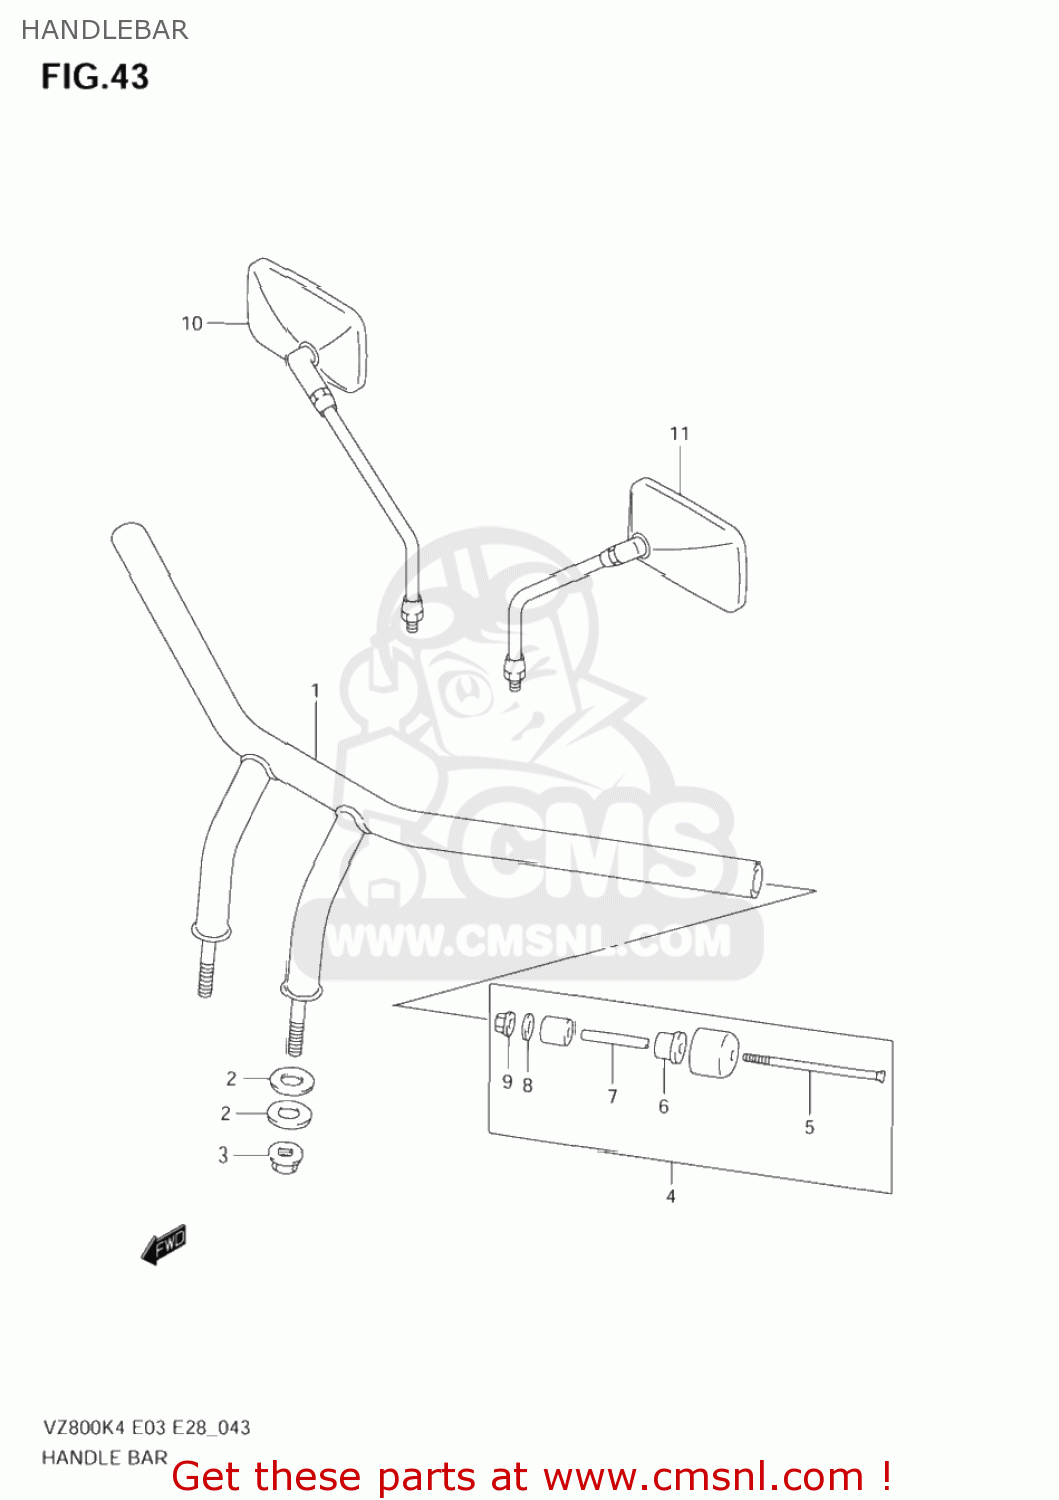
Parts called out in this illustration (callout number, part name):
1	HANDLEBAR
2	CUSHION,HANDLEBAR
3	NUT 12MM
4	BALANCER SET,HANDLEBAR
5	SCREW(6X110)
6	EXPANDER,HANDLE BALANCER NO.2
7	SPACER,EXPANDER
8	WASHER(6.5X18X2)
9	NUT
10	MIRROR ASSY, REAR VIEW RH
11	MIRROR ASSY,RH
